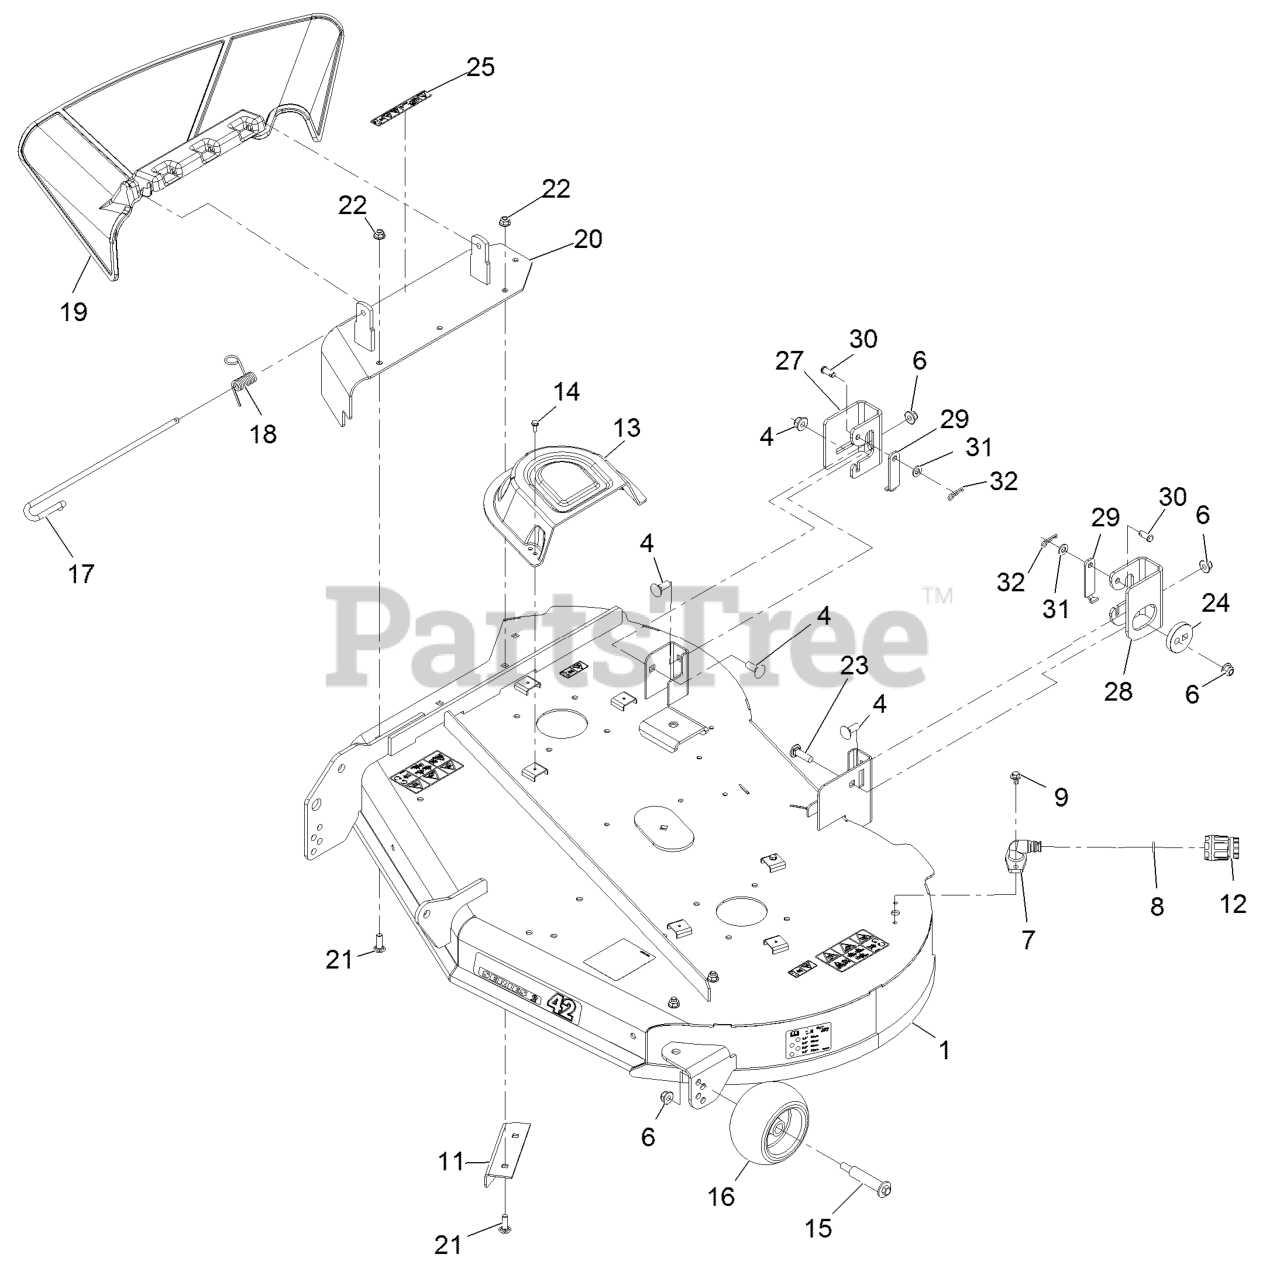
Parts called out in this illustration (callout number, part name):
1	42" DECK AND DECAL ASM (S
4	BOLT-CARR
6	NUT-HF, NI
9	SCREW-HHFTF
11	BAFFLE-CUTOFF
12	CONNECTOR-HOSE
13	COVER-BELT
14	SCREW-TAPTITE
15	BOLT-SHOULDER
16	ROLLER-SCALP, ANTI
17	PIN-CHUTE
18	SPRING-TORSION
19	DEFLECTOR-DISCHARGE
20	DISCHARGE COVER ASM
21	SCREW-CARR
22	NUT-HF, NI
23	Bolt-Carriage 3/8-16 X 1 1/4
24	ECCENTRIC
25	DECAL-DANGER
27	BRACKET - HANGER, RR
28	BRACKET - HANGER, LR
29	LINK - DECK RETENTION
30	PIN-CLEVIS
31	WASHER-PLAIN
32	PIN-COTTER
